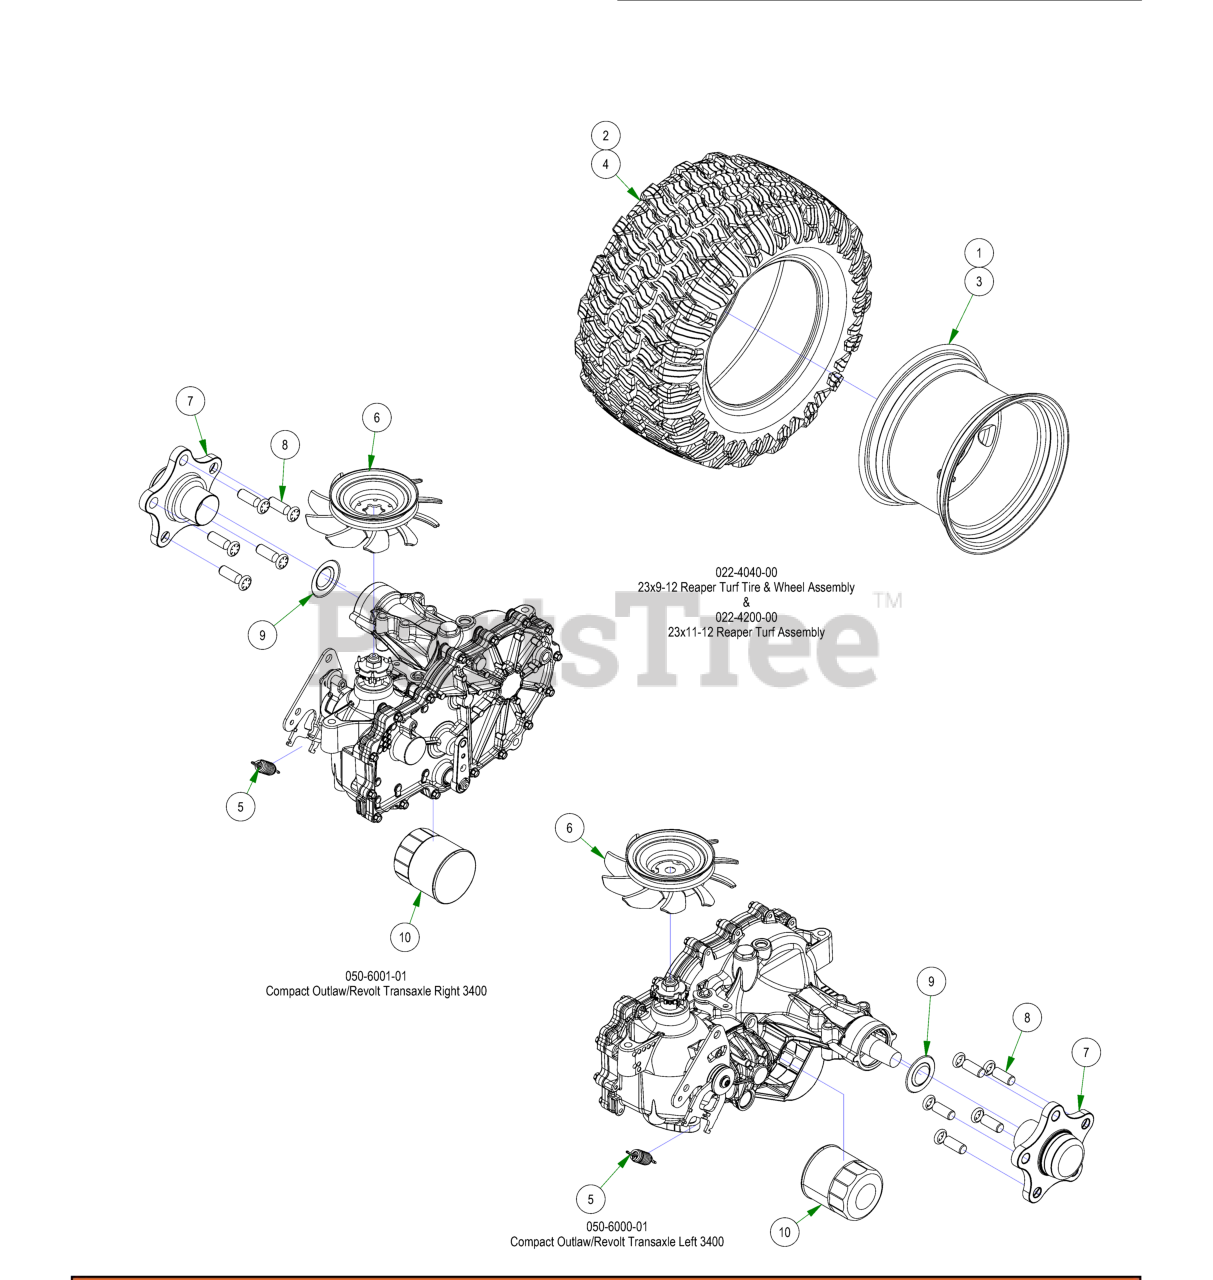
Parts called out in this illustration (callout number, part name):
1	12x7" Black Wheel
2	23x9-12 Reaper Turf Tire Only
3	12x8.5 Black Wheel
4	Tire, 23/11x12 Reaper Turf
5	Gold Transaxle Spring
6	Fan/Pulley Kit for CZT Also for the 050-0075-01
7	5 Bolt Hub Kit
8	Transaxle Wheel Studs/ Drum Brake Studs
9	Seal Kit for 3400 Transaxle fits the 050-6000-01 / 050-6001-01
10	ZT Hydraulic Filter
